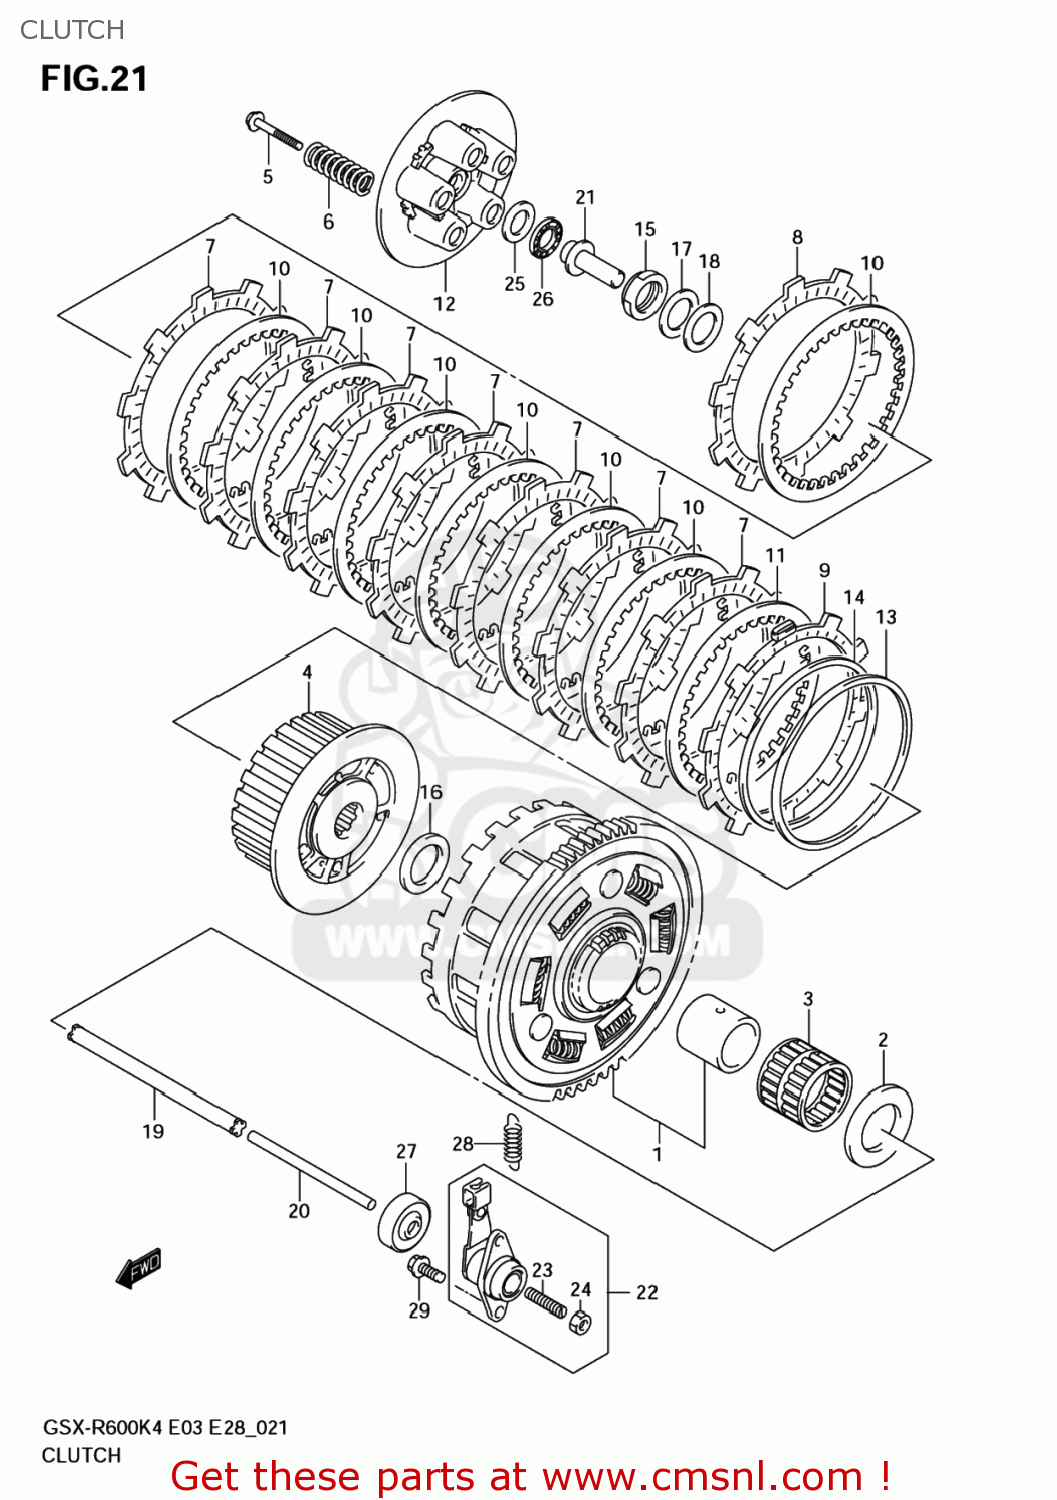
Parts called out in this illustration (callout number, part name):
1	GEAR ASSY,PRI DRIVEN
2	WASHER(25X54X2.4)
3	BEARING(35X40X29.8)
4	HUB,CLUTCH SLEEVE
5	BOLT,CLUTCH SPRING
6	SPRING,CLUTCH
7	PLATE,CLUTCH DRIVE NO.1 (NAS)
8	PLATE,CLUTCH DRIVE (NAS)
9	PLATE,CLUTCH DRIVE (NAS)
10	PLATE,CLUTCH DRIVEN NO.2 (NAS)
11	PLATE,CLUTCH DRIVEN NO.1 (NAS)
12	DISC,CLUTCH PRESSURE
13	SEAT,CLUTCH PLATE WAVE WASHER
14	WASHER,CLUTCH PLATE WAVE
15	NUT
16	WASHER(25X50X2.5)
17	WASHER
18	SHIM(25X38X1)
19	ROD,CLUTCH
20	ROD,CLUTCH PUSH,L
21	PIECE,CLUTCH PUSH
22	SCREW ASSY,CLUTCH RELEASE
23	SCREW(6X25)
24	NUT
25	WASHER(15.5X28X1)
26	BEARING(15X28X2)
27	SEAL,OIL(6X34X10)
28	SPRING
29	BOLT
